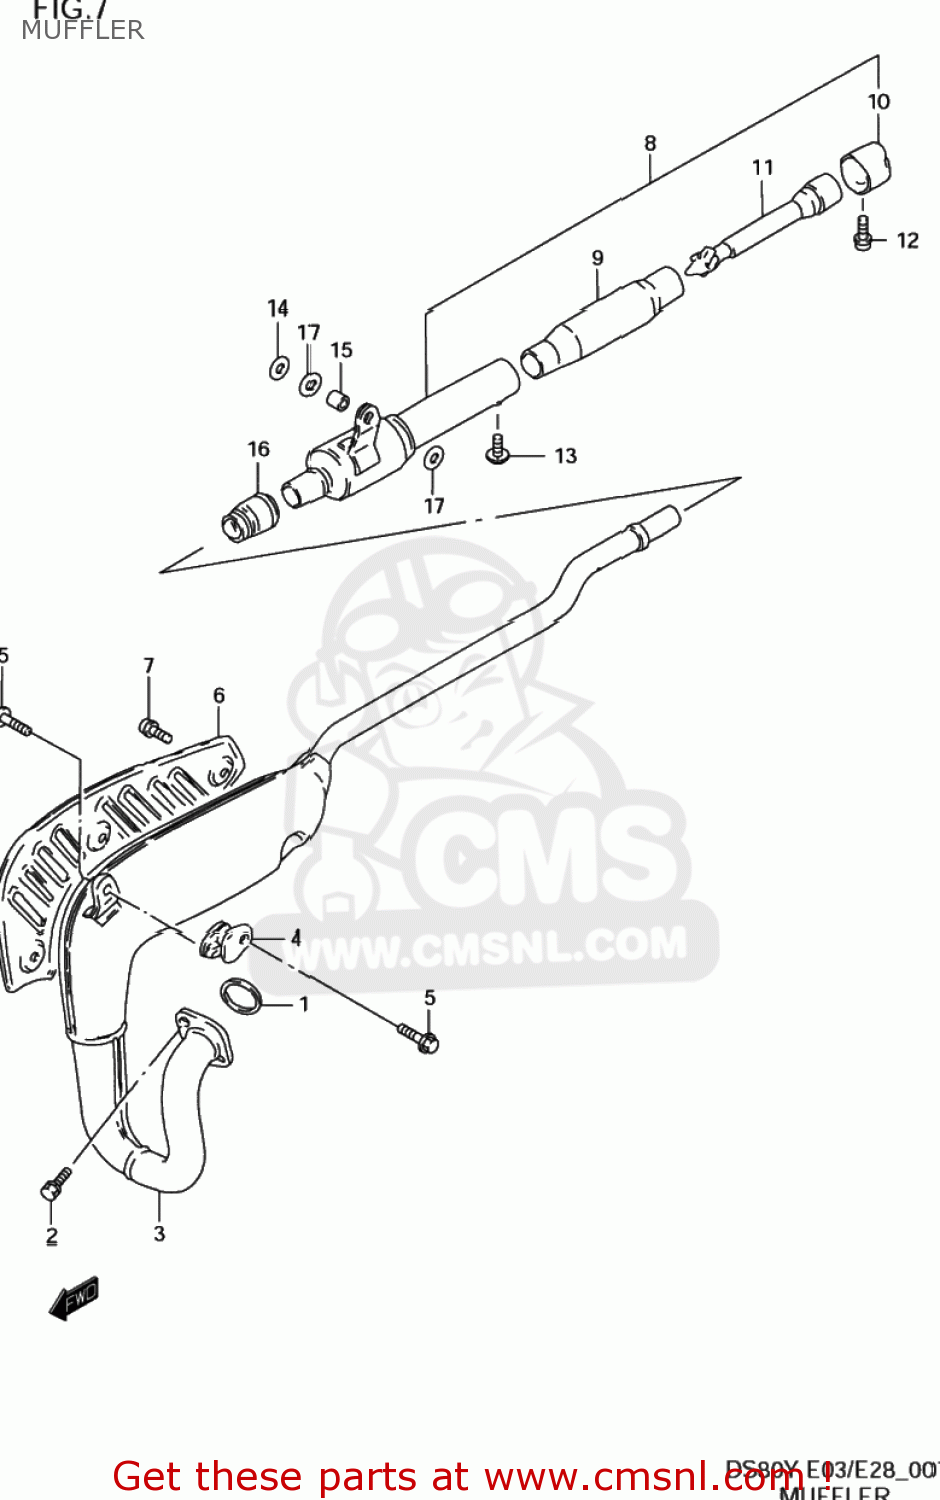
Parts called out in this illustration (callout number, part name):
1	GASKET,EXHAUST (NAS)
2	BOLT
3	BODY,MUFFLER 1ST
4	DAMPER,MUFFLER SUPPORT
5	BOLT
6	COVER,MUFFLER
7	SCREW
8	MUFFLER ASSY,2ND
9	SHELL,ARRESTER
10	CUTTER,MUFFLER TAIL
11	TUBE,CLEAN OUT
12	SCREW
13	SCREW
14	WASHER
15	SPACER,8.5X14X9
16	CONNECTOR,MUFFLER
17	CUSHION
